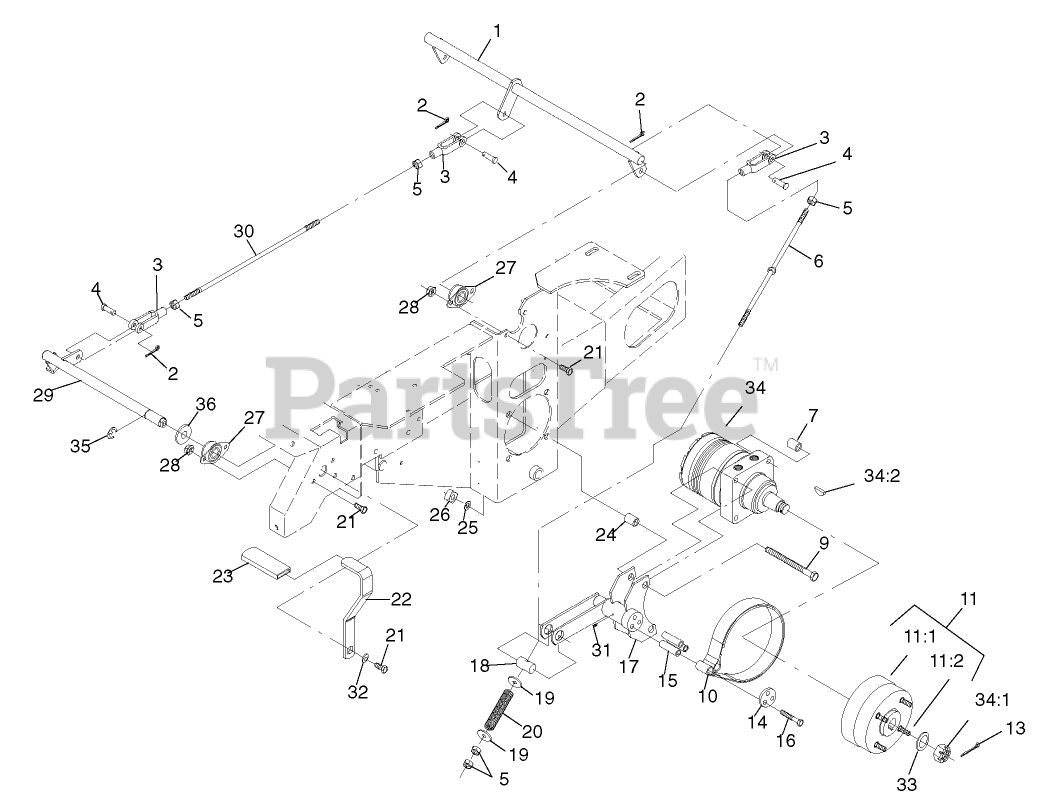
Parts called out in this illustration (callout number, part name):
1	CRANK-BRAKE, PARK
2	PIN-COTTER
3	YOKE-LINKAGE, BRAKE
4	PIN-CLEVIS
5	NUT-HEX
6	ROD-BRAKE
7	SPACER-WHEEL
9	SCREW-HH
10	BAND-BRAKE
11	WHEEL HUB ASM
11:1	HUB-WHEEL
11:2	STUD-WHEEL
13	PIN-COTTER
14	RETAINER-BAND, BRAKE
15	SPACER
16	SCREW-HH
17	BRACKET-BRAKE
18	PIN-TRUNION
19	WASHER-FLAT
20	SPRING-BRAKE
21	SCREW-HH
22	HANDLE-BRAKE, PARK
23	GRIP-LEVER
24	SPACER-WHEEL
25	WASHER-LOCK
26	NUT-SQUARE
27	BEARING-FLANGE, SIDE
28	NUT-HHF, WHIZ
29	SHAFT-BRAKE, PARKING
30	LINKAGE-HANDLE, BRAKE
31	FITTING-GREASE
32	WASHER-BELLEVILLE
33	WASHER-SPACER
34	MOTOR-WHEEL
34:1	NUT-HH
34:2	KEY-WOODRUFF
35	E-RING
36	WASHER-FLAT
